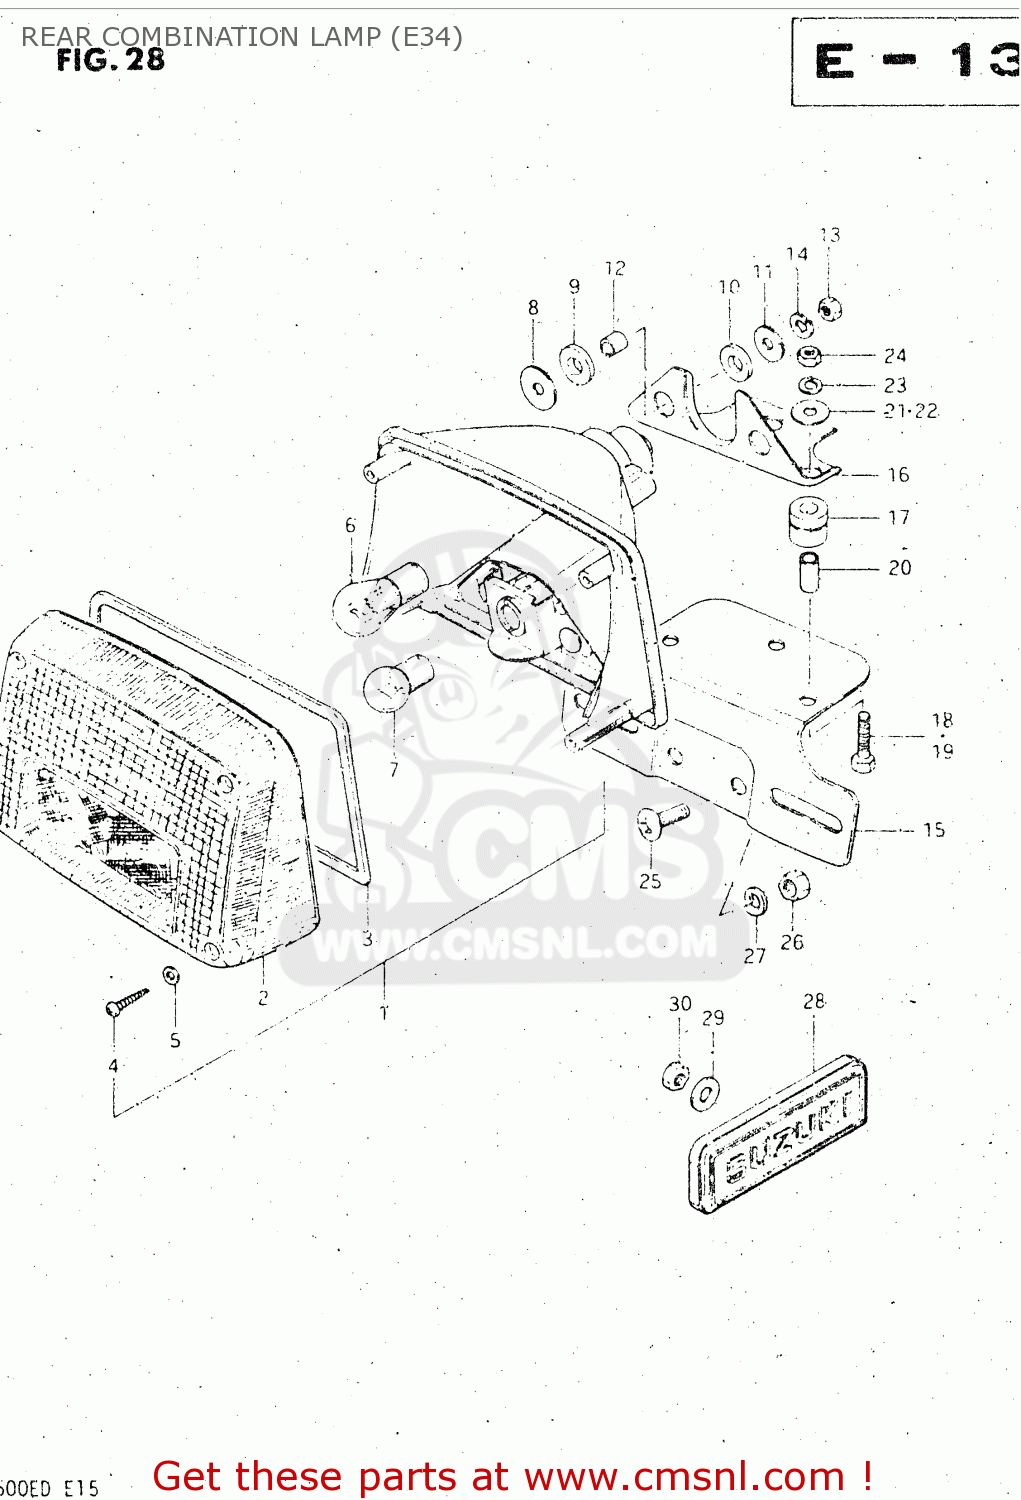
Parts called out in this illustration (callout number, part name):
1	LAMP, REAR COMBINATION
2	LENS
3	GASKET (NAS)
4	SCREW,REAR COMBINATION LAMP
5	GASKET (NAS)
6	BULB(12V21/5W)
7	BULB
8	WASHER
9	CUSHION
10	CUSHION
11	WASHER(6,5X22X1.6)
12	SPACER(6.1X9X7.5)
13	NUT
14	LOCK WASHER
15	BRACKET, LICENCE PLATE
16	BRACKET,LICENSE PLATE
17	CUSHION, BRACKET
18	BOLT
19	BOLT
20	SPACER (6.4X9X15.5)
21	WASHER
22	WASHER
23	LOCK WASHER
24	NUT
25	SCREW
26	NUT
27	LOCK WASHER
28	EMBLEM, REAR SIDE
29	WASHER
30	NUT
